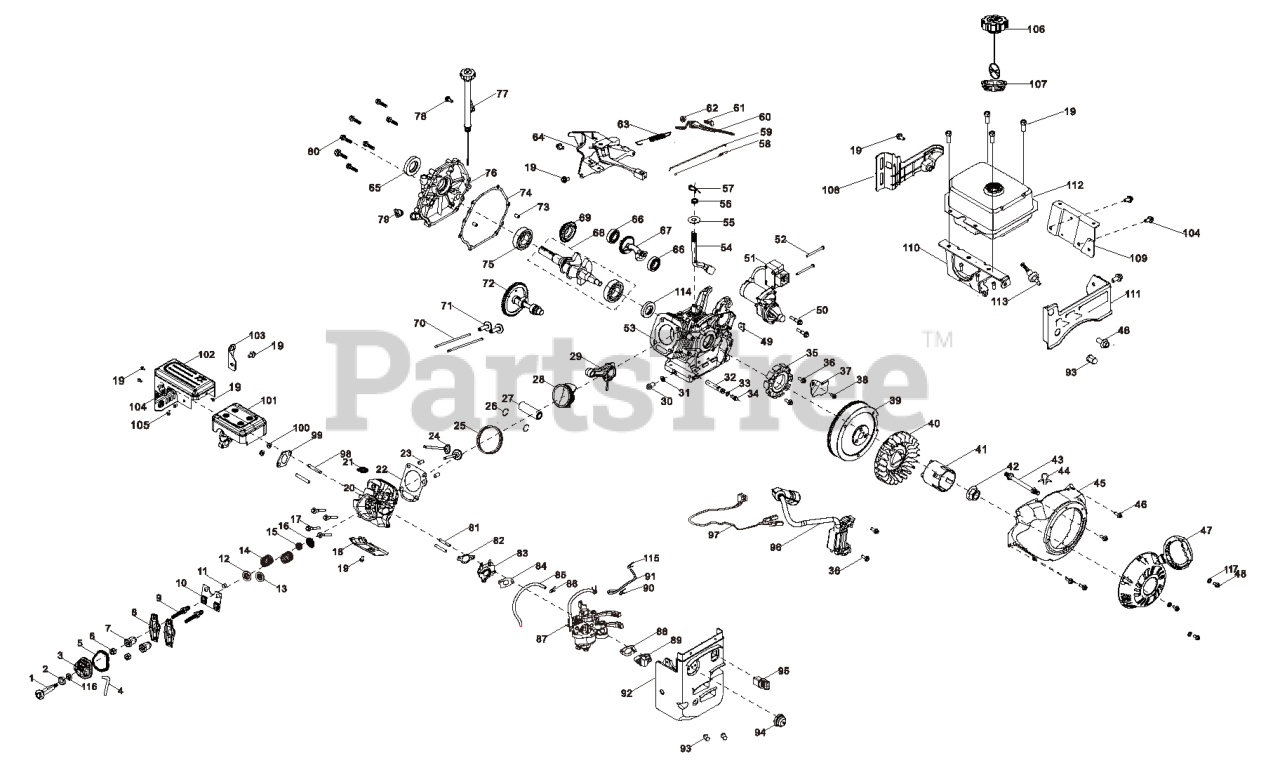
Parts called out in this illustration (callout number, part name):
1	BOLT, VALVE COVER
2	SEAL, VALVE COVER
3	COVER, VALVE
4	TUBE, BREATHER
5	GASKET, COVER CYL HEAD
6	NUT, VALVE LOCK
7	NUT, VALVE ADJUSTING
8	ROCKER, VALVE
9	ROCKSHAFT BOLT
10	ASM, LIFTER STOPPER PLATE
11	CLAMP, VALVE LOCK
12	EXHAUST VALVE SPRING SEAT
13	SEAT, VALVE SPRING
14	SPRING, VALVE
15	GUIDE, SEAL
16	RETAINER, VALVE SPRING
17	BLT, CYL HEAD
18	SHROUD, CYLINDER BODY
19	BLT, HEX-FLG M6X12
20	HEAD SUBASSEMBLY, CYL
21	SPARK PLUG - PLATINUM
22	GASKET, CYL HEAD
23	POSITION PIN - TYPE A
24	VALVE SET
25	RING ASM, PISTON
26	CLIP, PISTON PIN
27	PIN, PISTON
28	PISTON
29	ROD, CONNECTING
30	BOLT, DRAIN PLUG
31	FLAT WASHER
32	TUBE, OIL DRAIN
33	FLAT WASHER - GRADE A
34	BOLT, DRAIN PLUG
35	COIL SUBASSEMBLY, CHARGE
36	BLT, HEX-FLG M6X28
37	CLAMP, CHARGE COIL
38	BOLT, M6X10 HEX FLANGE
39	FLYWHEEL SUBASSEMBLY
40	IMPELLER
41	PULLEY,STARTER
42	NUT, FLYWHEEL
43	STUD BOLT (BM=2D)
44	WIRE CLIP
45	SHROUD
46	BOLT, M6X12 GRADE B HEX FLANGE
47	STARTER ASSY, RECOIL
48	BOLT, M6X8 HEX FLANGE
49	PLUG, RUBBER
50	BOLT, M8X35 HEX FLANGE
51	STARTING MOTOR ASSEMBLY
52	SCREW, PAN HEAD M4X55X0.7
53	SUBASM, CRANKCASE
54	ARM, GOVERNOR
55	FLAT WASHER
56	OIL SEAL
57	COTTER PIN
58	SPRING, THROTTLE VLV RETURNING
59	ROD, GOVERNEOR
60	GOVERNOR BRACKET SUBASSEMBLY
61	BOLT, GOVERNOR SUPPORT
62	HEXAGON NUT WITH FLANGE
63	SPRING, GOVERNOR
64	CONTROL ASSY, THROTTLE
65	SEAL, OIL
66	DEEP GROOVE BALL BEARING
67	ASM, BALANCING SHAFT
68	ASM, CRANKSHAFT
69	GEAR ASSY, GOVERNOR
70	PUSH ROD, VALVE
71	TAPPET, VALVE
72	ASM, CAMSHAFT
73	POSITION PIN
74	GASKET, CRANKCASE
75	DEEP GROOVE BALL BEARING
76	COVER, CRANKCASE
77	DIPSTICK SUBASSEMBLY, OIL
78	BLT, HEX-FLG M6X25X1
79	PLUG SUBASSEMBLY, ENGINE OIL
80	BOLT, M8X40 HEX FLANGE
81	STUD BOLT (BM=2D)
82	GASKET, INLET
83	PLATE, CARBURETOR INSULATOR
84	CARBURETOR SEAL GASKET
85	LINE, PRIMER
87	ASM, CARBURETOR
88	AIR CLEANER SEAL GASKET
89	SEDIMENT CUP
90	PIPE CLAMP
91	TUBE, FUEL
92	BOX, HEATER
93	ACORN HEXAGON NUTS
94	BULB, PRIMER
95	ASM, STOP ENGINE SWITCH
95	KEY, STOP ENGINE SWITCH
95	ON/OFF PUSH KEY
96	COIL, IGNITION
97	WIRE, IGNITION COIL STOP ENGIN
98	STUD BOLT (BM=2D)
99	GASKET, EXHAUST OUTLET
100	LOCK NUT
101	MUFFLER ASSY.
102	COVER, SCALD RESISTANT
103	TRANSPORT HANGER
104	BOLT, M8X20 HEX FLANGE
105	BOLT, M6X16 HEX FLANGE
106	CAP, FUEL
107	FUEL GAUGE
108	FUEL TANK SHIELD 2
109	FUEL TANK INSTALL REAR BRKT
110	FRAME, FUEL TANK INSTALLATION
111	SHIELD,FUEL TANK
112	FUEL TANK
113	OUTLET WITH FILTER
114	SEAL, OIL
115	PIPE CLAMP
116	COVER, CYL HEAD BOLT SEAL RING
117	WSHR-FL, GR A
NS	KIT,HIGH ALT MAIN JET 3K-6K FT
NS	KIT,HIGH ALT MAIN JET 6K-8K FT
NS	TOOL, SPARK PLUG
